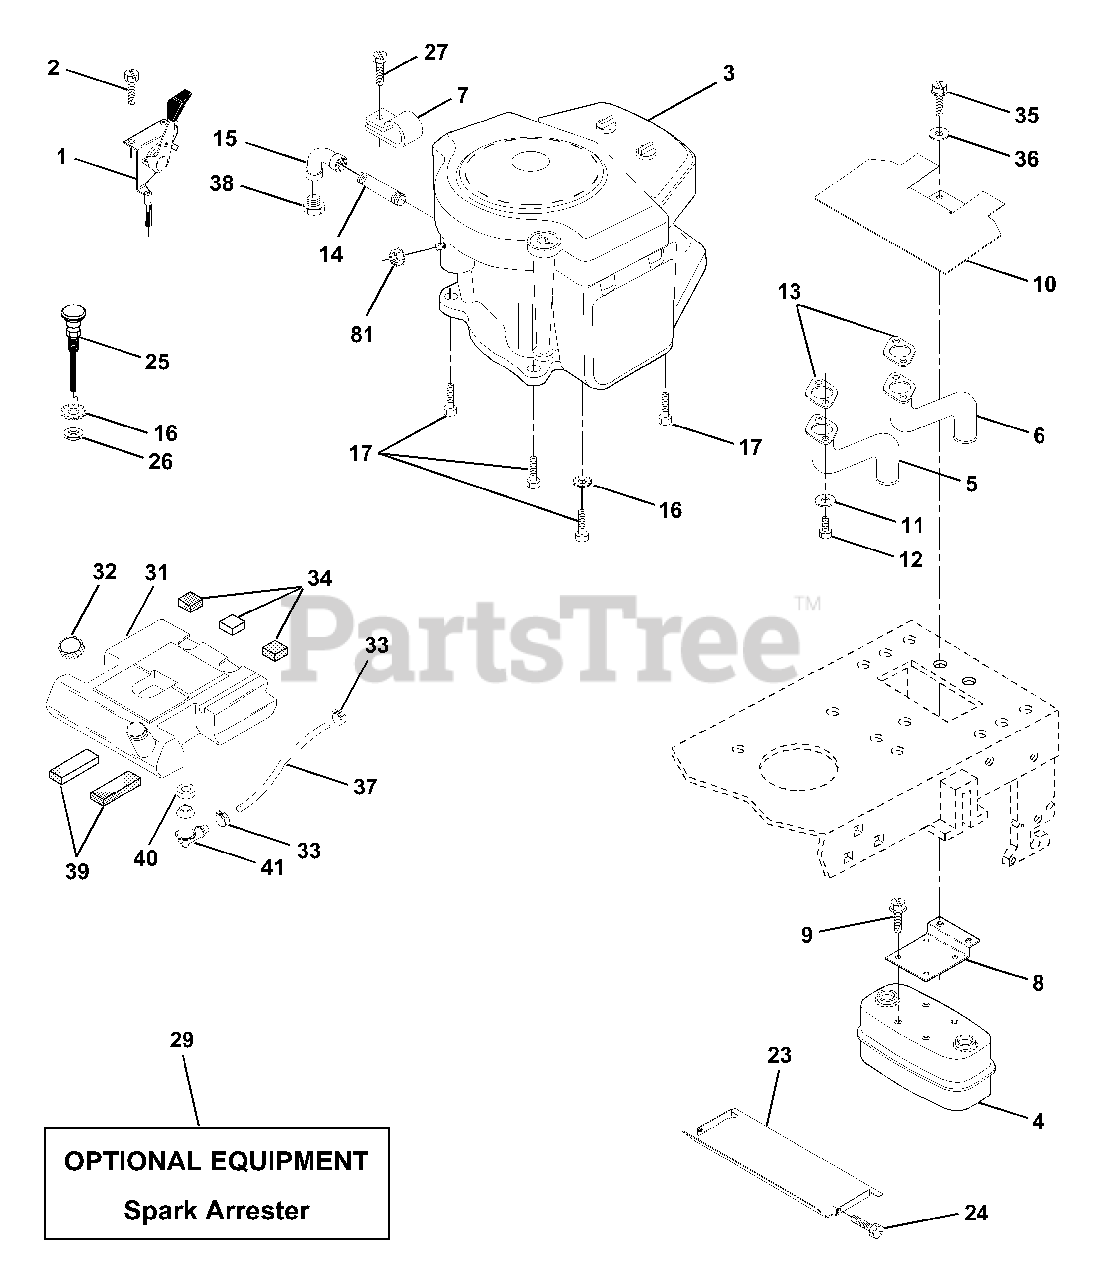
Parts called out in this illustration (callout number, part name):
1	Control Throt Rh Hg 44.75
2	Screw Hex Thd Cut 1/4-20x5/8 T
4	Muffler LT B&S
5	Tube Manifold LH
6	Tube Manifold RH
7	Clamp Tube Double Engine
8	Bracket Muffler Mounting
9	Screw Hex Wsh Thd Cut 1/4-20
10	Shield Heat LT
11	Washer Lock Hvy Helical 1/4
12	Bolt fin Hex 1/4-20 Unc x .75
13	Muffler Gasket
14	Nipple Pipe 3/8 Npt X 4-1/2"
15	Elbow Std 90 Degree 3/8-18 Npt
16	Washer Lock Ext Tooth 3/8
17	Screw Thdrol 3/8-16 x 1-1/2
23	Shield Heat Browning LT/YT
24	Screw Tap Hex #10-24unc X 1/2
25	Choke Control
26	Nut, Fin Hex 3/8-24 Unf
27	Screw Slftp #10-24 x 1/2 Tt-B
29	Kit Spark Arrestor (Flat Scrn)
31	Tank Fuel 3 50 Rear
32	Cap Asm Fuel W/sym Vented
33	Clamp Hose Blk
34	Pad, Spacer
35	Screw Thdrol 5/16-18 x 3/4
36	Washer 13/32 x 1-1/4 x 12 Ga.
37	Line Fuel 54"
38	Plug Oil Drain
39	Pad, Idler
40	Bushing
41	Stem Tank Fuel
81	Nut Keps Hex 1/4-20 Unc
